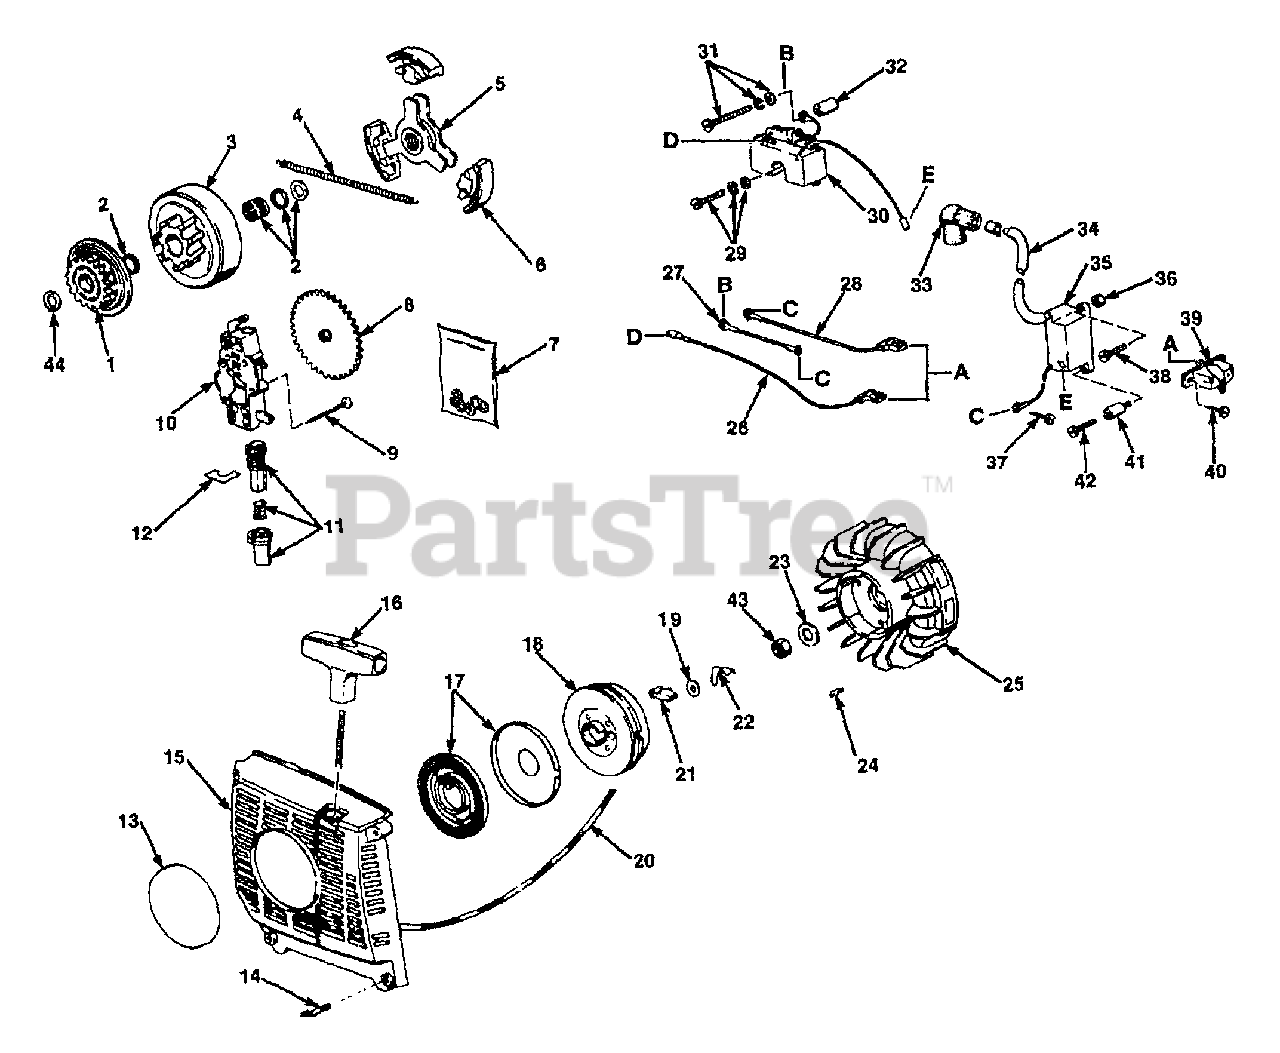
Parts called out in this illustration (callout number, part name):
1	ACTIVATOR-3/8 P., 7T
2	NEEDLE BEARING KIT
3	SPROCKET & DRUM, 3/8 P, 7 T.
4	SPRING-Clutch
5	SPRING-Clutch
6	SHOE-Clutch
7	KIT-Pump repair
8	GEAR & HUB ASSEMBLY
9	SCREW (4.2 x 32)
10	OIL PUMP ASSEMBLY
11	REGULATOR REPAIR KIT
12	PLATE-Support
13	DECAL-Starter (340)
14	SCREW (5 x 20)
15	HOUSING-Starter
16	GRIP-Starter
17	SPRING & CONTAINER
18	PULLEY-Starter
20	STARTER PAWL & ROPE KIT
21	STARTER PAWL
22	CLIP-Retaining
23	WASHER-Flat
24	KEY-Woodruff
26	WIRE-Ground
27	CABLE-Insulated
28	CABLE-Insulated
29	SCREW-F.H. (5 x 20)
30	MODULE & CORE
31	SCREW-F.H. (5 x 30)
33	TERMINAL-Spark plug
34	TUBING-Silicon 3 1/2"
35	COIL-Ignition
37	SCREW (3.9 x 13)
38	SCREW-F.H. (4 x 14)
39	SWITCH (on/off)
40	SCREW (3.5 x 13)
42	SCREW (F.H. 4 x 18)
43	NUT-Hex
